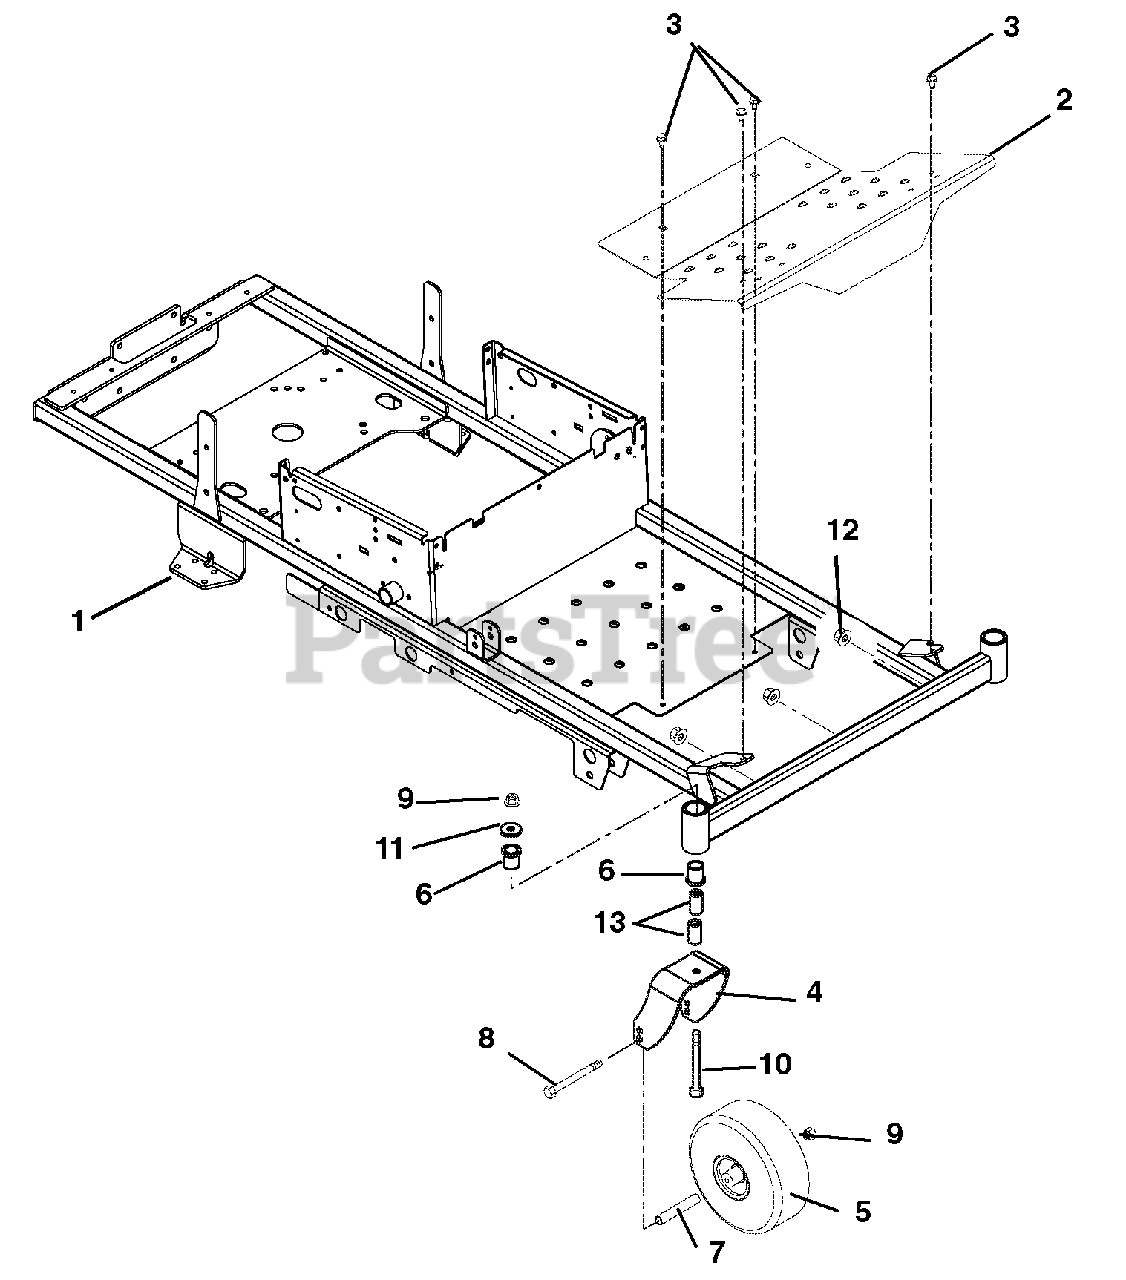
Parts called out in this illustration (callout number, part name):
1	WMT, ZOOM FRAME
2	FOOTREST, MZ/ZOOM
3	@SCR-TAP .31-18X.50 HWH TR YWZ
4	FORK, CASTER- WELDED
5	TIRE/WHEEL ASSY, 11X4-5
6	BSHG-FLG 1.00X1.25X1.50X1.50EP
7	SPACER, ROLLED WHEEL
8	@BLT-HEX .50-13X6.50 GR5 YWZC
9	@NUT-LK-NYL-FLG .50-13 YWZC
10	@BLT-HEX .50-13X5.00 GR5 YWZC
11	WSHR-FL-STL.511X1.441X.125 YWZ
12	@NUT-LK-NYL-FLG .63-11 YWZC
13	SPACER, CASTER .50X1.00X1.84
